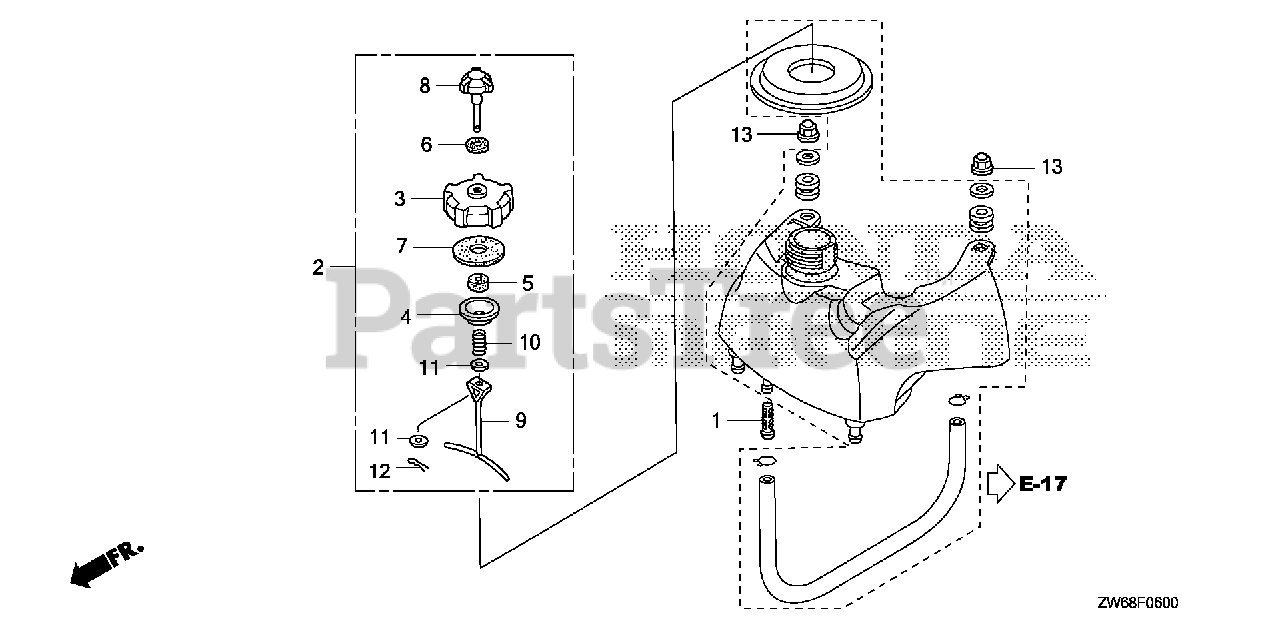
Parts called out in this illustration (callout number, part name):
1	FILTER, FUEL
2	CAP ASSY., FUEL TANK
3	BODY, FUEL CAP
4	INNER, FUEL CAP
5	SPONGE, FUEL CAP BREATHER
6	GASKET, VALVE
7	GASKET, FUEL CAP
8	VALVE, BREATHER
9	LINK, FUEL CAP
10	SPRING, FUEL CAP
11	WASHER, PLAIN (4MM)
12	PIN, LOCK (4MM)
13	NUT, CAP (6MM)
